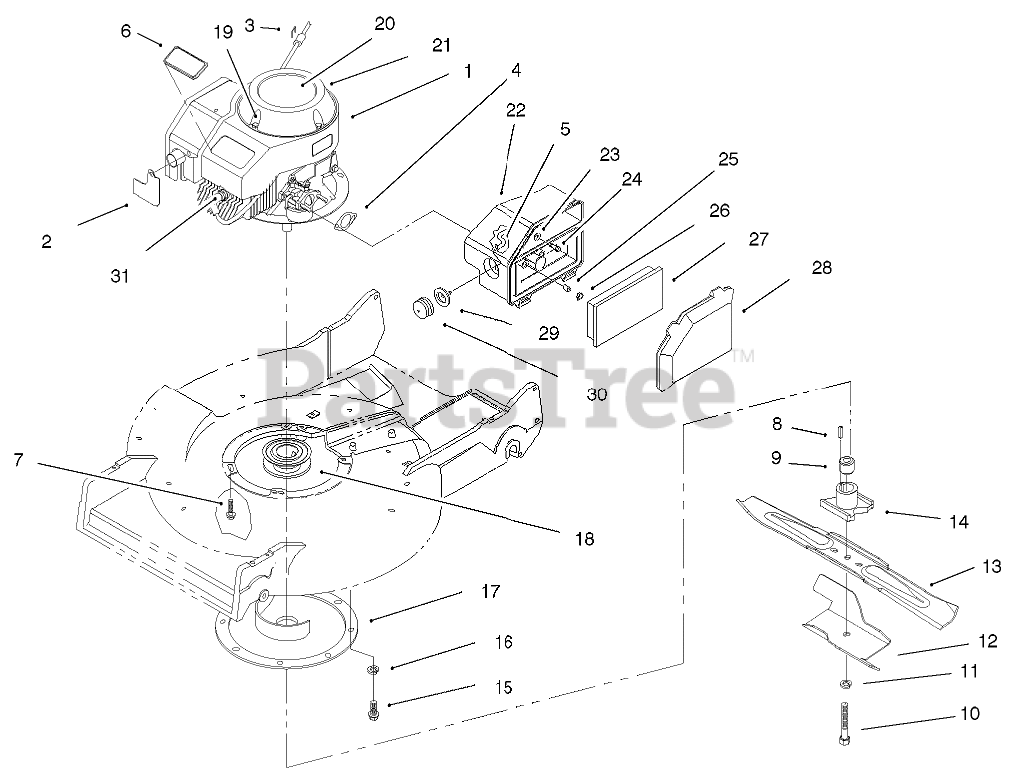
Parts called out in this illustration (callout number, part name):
1	ENGINE-121CC 2 CYC
2	EXTENSION-MUFFLER GUARD
3	STAPLE
4	GASKET-AIR CLEANER
5	HOSE-PRIMER
7	SCREW-HHF
8	KEY-SQUARE
9	SPACER-BLADE RETAINER
10	SCREW-BLADE
11	WASHER-LOCK
12	STIFFENER-BLADE
13	Blade
14	RETAINER-BLADE
15	SCREW-HWHTF
16	WASHER-LOCK, INTERNAL
17	PROTECTOR-CRANKSHAFT
18	PULLEY-DRIVER
20	DECAL-2 CYC RECOIL
21	RECOIL ASM
22	BODY-AIR CLEANER
23	WASHER-FLAT
24	SCREW-HH
25	SPACER
27	ELEMENT-AIR CLEANER
28	COVER-AIR CLEANER
29	BODY-PRIMER
30	BULB-PRIMER
31	Sparkplug
